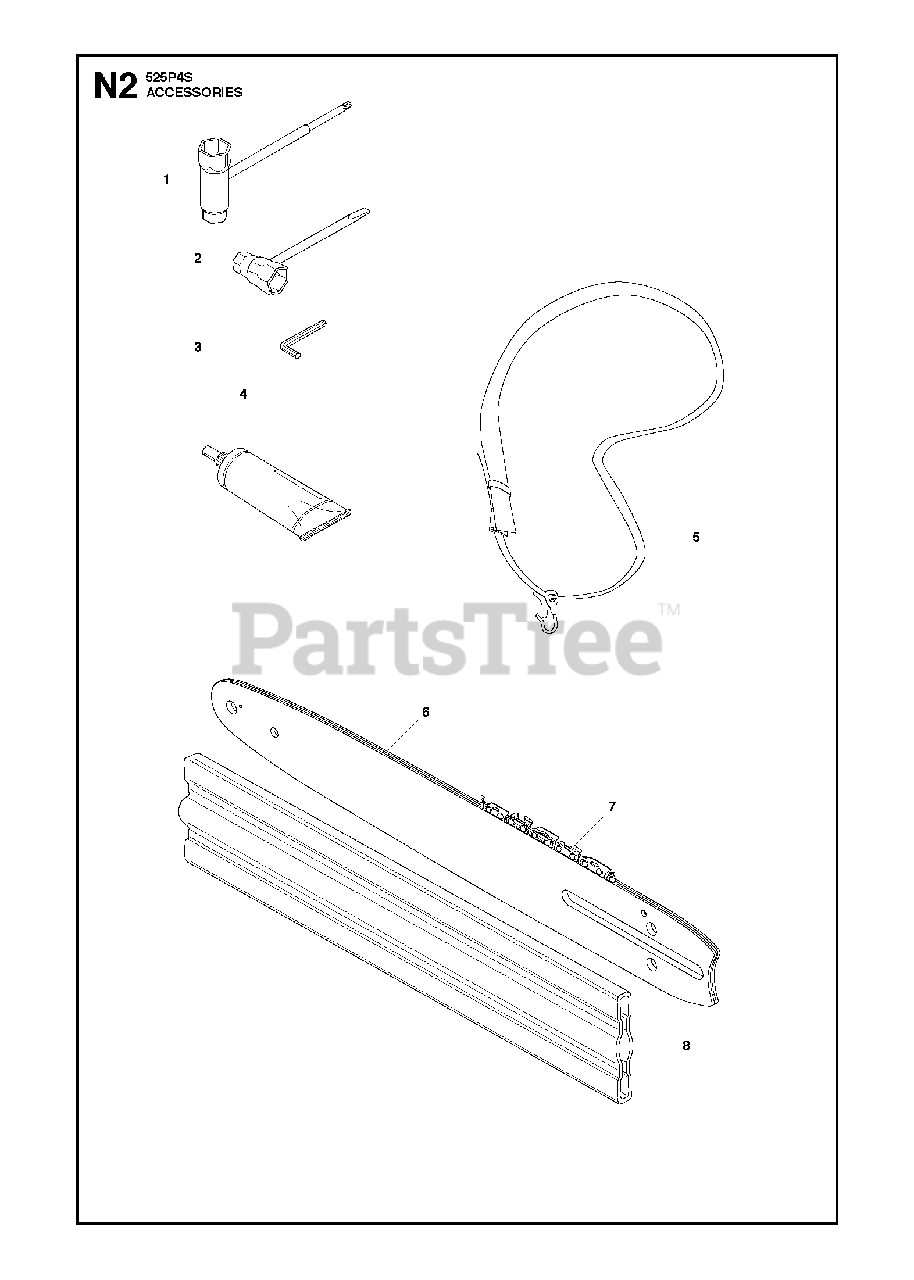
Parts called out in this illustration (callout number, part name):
1	COMBINATION WRENCH TORX
2	COMBI TOOL
4	GREASE
5	STRAP
6	Guide Bar, 10" HL280-40 3/8" .050
6	Guide Bar, 12" Hl280-45 3/8 .050
7	Saw Chain, 10" H37-40 3/8 Mini, .050
7	Saw Chain, 12" H3745 38.050
